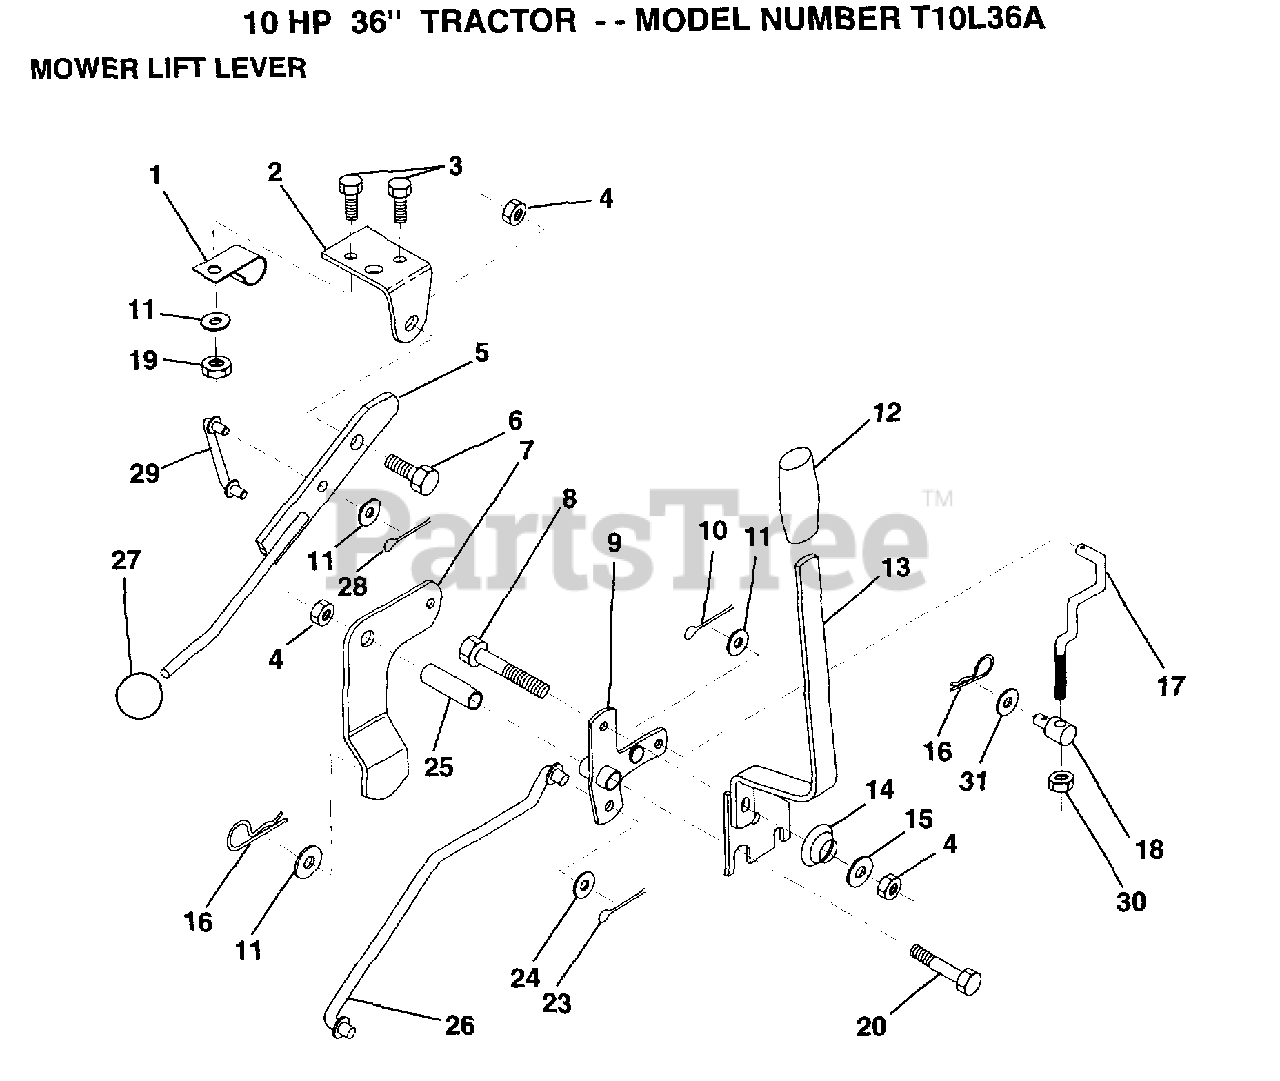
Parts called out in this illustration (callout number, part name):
1	"CLIP,INSULATOR"
2	BRKT CLUTCH
3	BOLT
4	NUT
5	CLUTCH LEVER AS
6	"BOLT, SHOULDER LT"
7	MWR CLUTCH ARM AS
8	BOLT
9	"BELLCRANK,LIFT"
10	COTTER PIN
11	WASHER
12	GRIP HANDLE
13	HANDLE.ASM.LIFT
14	SPRING COMPRESSIO
15	WASHER T
16	SPRING.RETAINER
17	"LINK,LIFT FRT"
18	TRUNION
20	BOLT
23	PIN COTTER 1/8
25	TUBE SPACER
26	ROD LIFT MOWER
27	KNOB T(3/8 HOLE)
29	CLUTCH LINK
30	NUT
31	WASHER
